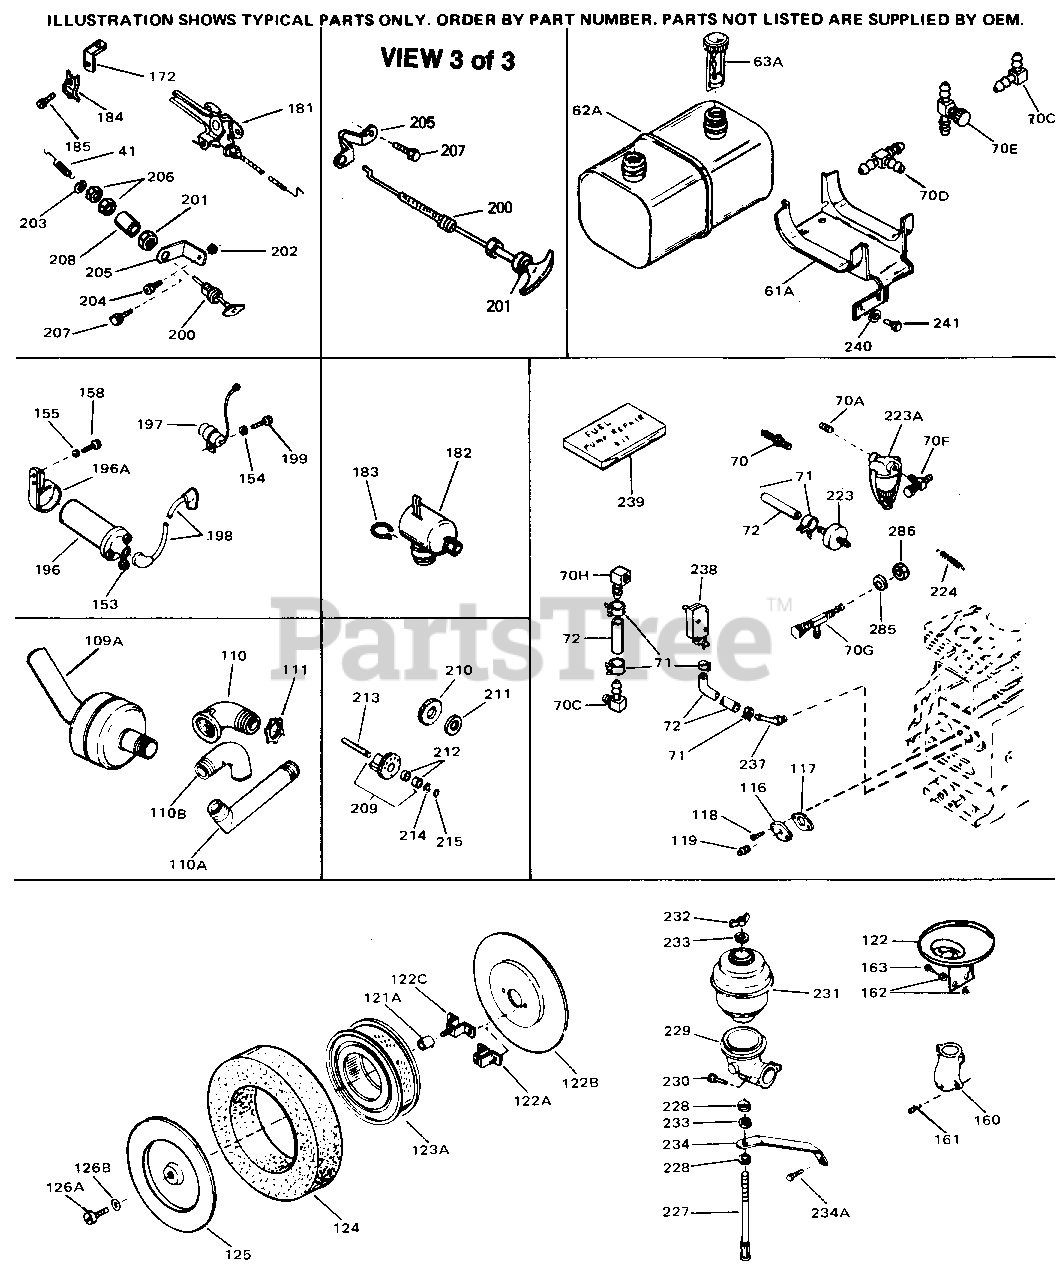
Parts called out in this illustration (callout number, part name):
41	Spring, Governor
71	Fuel Line Clamp
72	Fuel Line (8.62") equired)
72	Fuel Line (Braided) (16") Use as requ ired
72	Fuel Line (Braided) (32") Use as requ ired
72	Fuel Line (Braided) (48") Use as requ ired
119	Plug, Pipe, 1/8-27 (Use as required)
119	Oil Drain Plug
172	Bracket, Choke control
184	Conduit Clip
185	Screw, 10-32 x 3/8"
237	Fitting, Fuel
238	Fuel Pump, Impulse
239	Repair Kit, Impulse fuel pump
